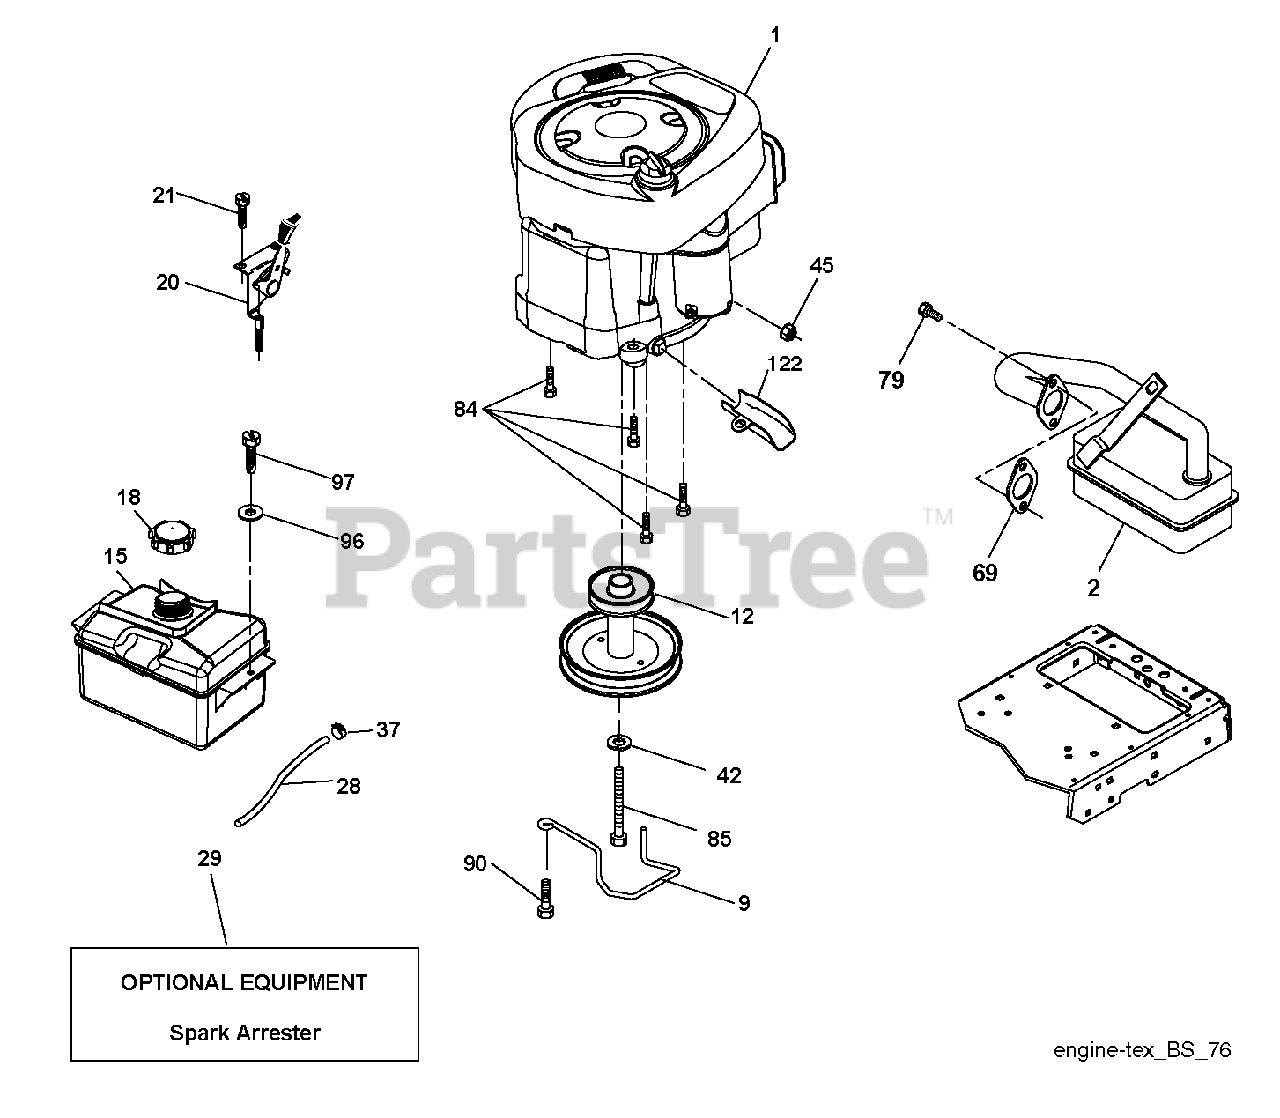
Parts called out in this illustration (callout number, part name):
2	MUFFLER.LT.BRIGGS.14HP.IC/OHV
9	KEEPER.BELT.ENGINE
12	PULLEY ENGINE
15	FUEL.TANK.ASM.1.5.GAL.NON-EPA
18	CAP ASM.FUEL.2.25"FR.
21	SCREW.#10 X 0.750.BOS (2 2)
28	LINE.FUEL.20
29	KIT.SPARK ARRESTOR(392390 B&S)
37	HOSE CLAMP
42	LOCKWASHER
45	NUT
79	SCREW.SOCKET HD.5/16-1
84	SCREW.3/8-16
85	BOLT HEX 7/16-20X4-1/4"
90	SCREW 3/8-16X1
97	SCREW HEXWSHR 1/4-20X3/4
122	EXTENSION DRAIN OIL
